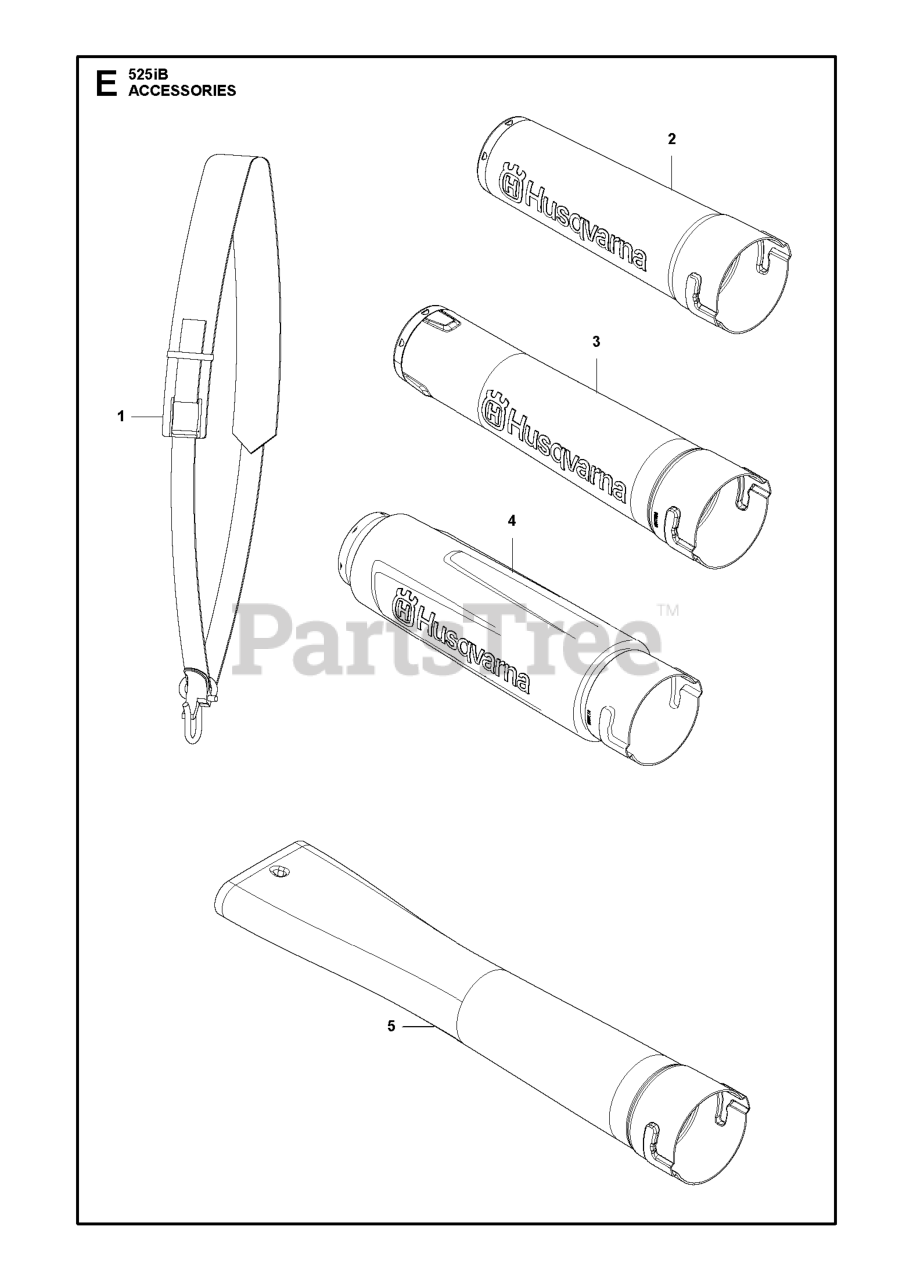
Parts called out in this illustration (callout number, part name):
1	Harness-w/o warning
2	TUBE ASSY
3	TUBE ASSY NOZZLE 536LIBX
4	TUBE ASSY NOZZLE SILENCER
5	BLOWER NOZZLE FOR 320IB
